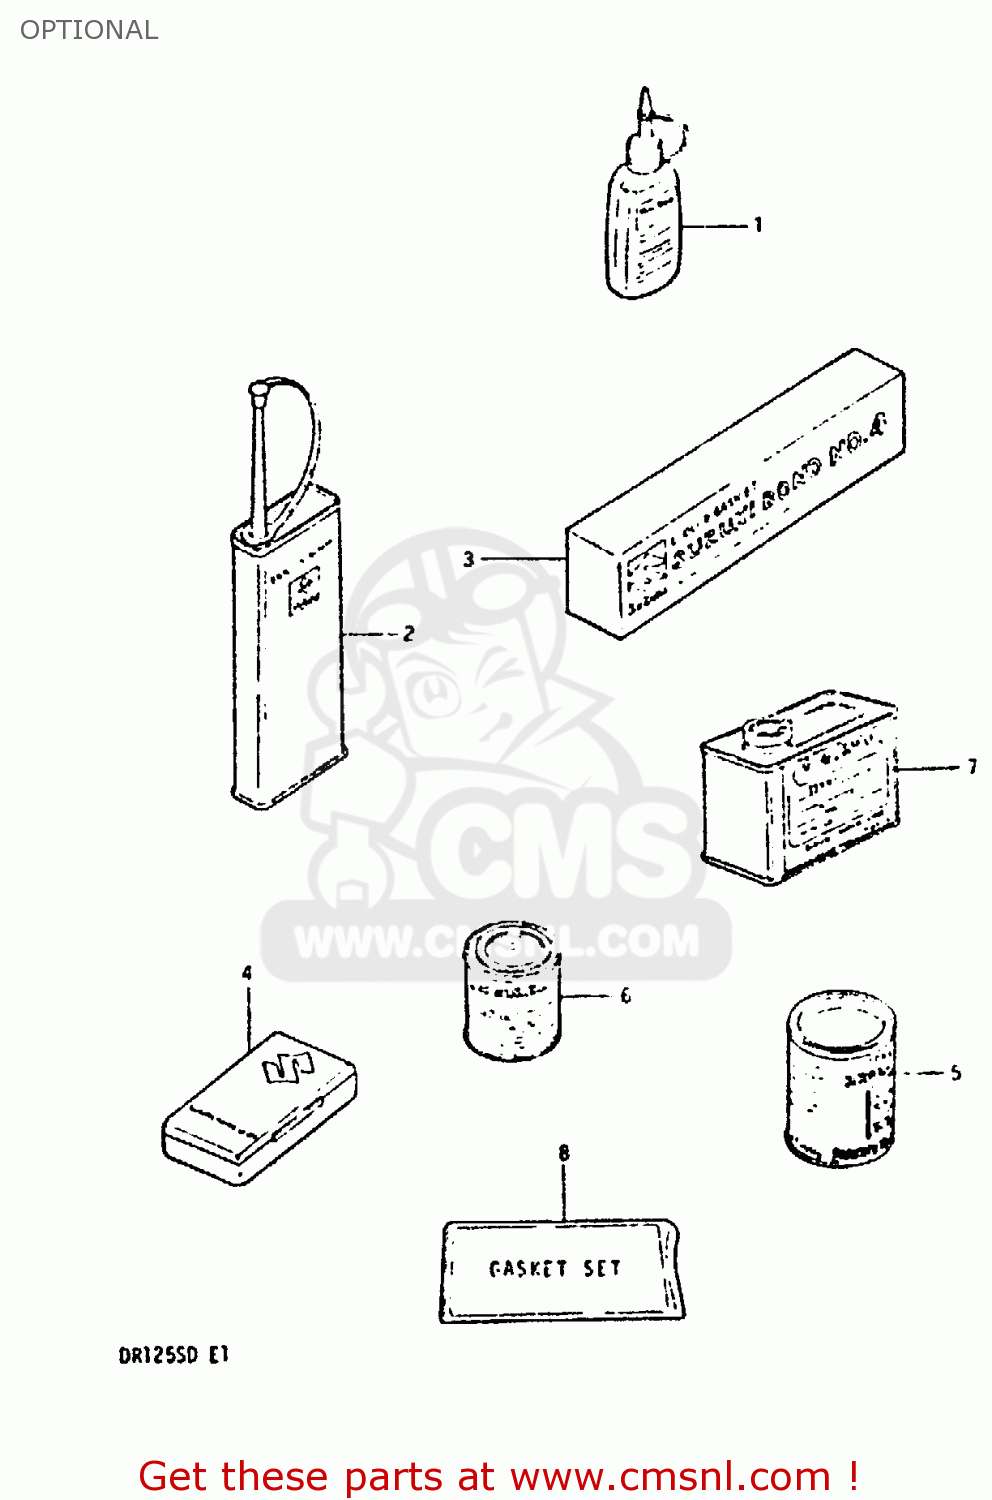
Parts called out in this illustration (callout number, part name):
1	THREAD LOCK NO
2	THREAD LOCK NO.1401 CLEAR 200G
3	BOND 1104
4	TUBE REPARING TOOL
5	GREASE(C)EP2 LITHIUM 150G
6	PAINT,BLACK
7	PAINT (BLACK)
8	GASKET SET
